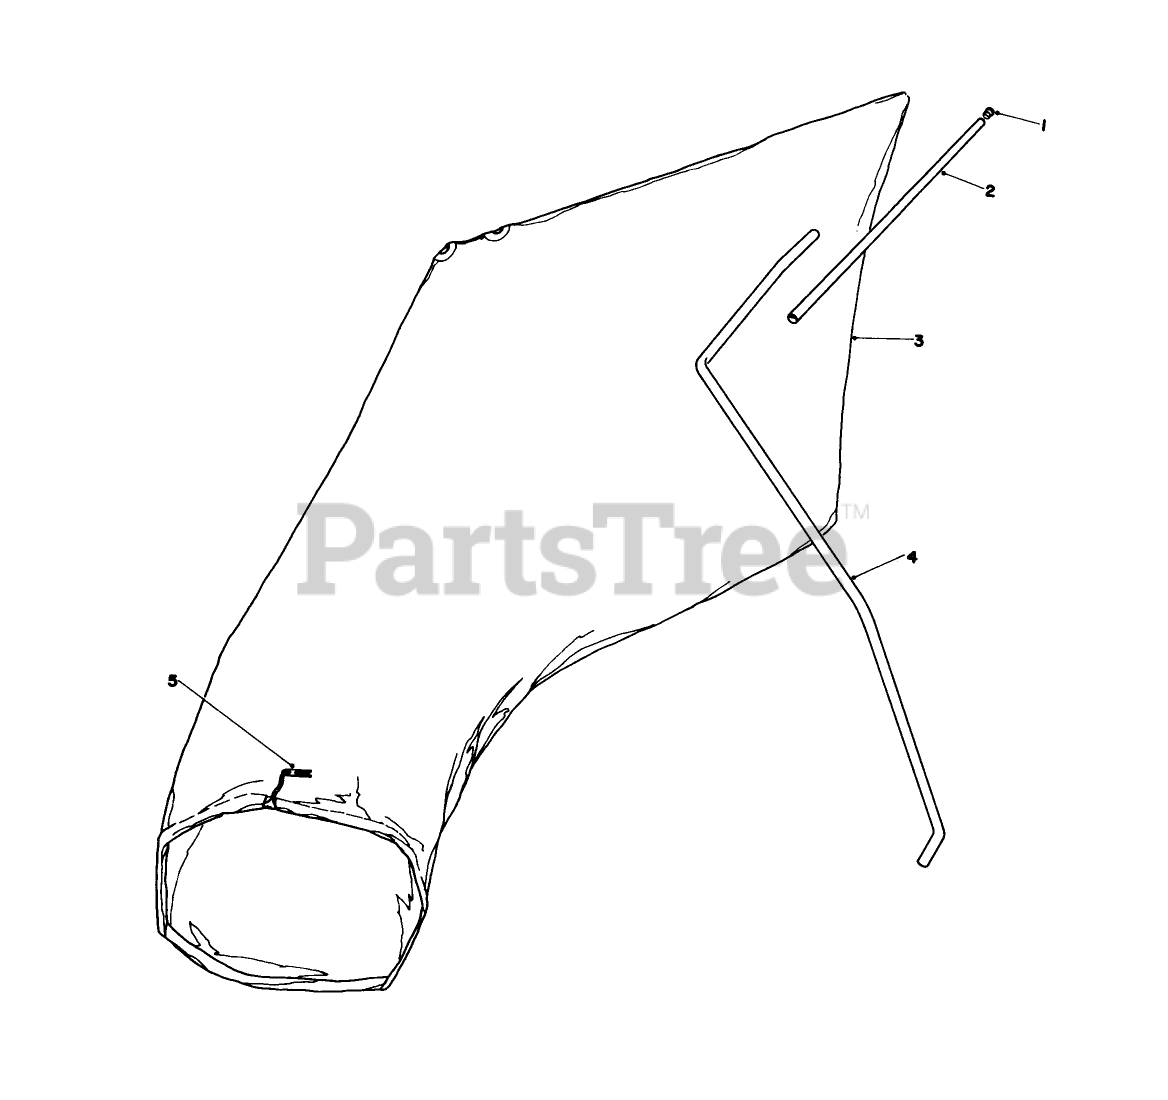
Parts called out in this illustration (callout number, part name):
2	BAG HANGER TUBE
3	Bag (Incl. Ref. #5)
4	Hanger Rod
5	BAG CORD FASTENER
